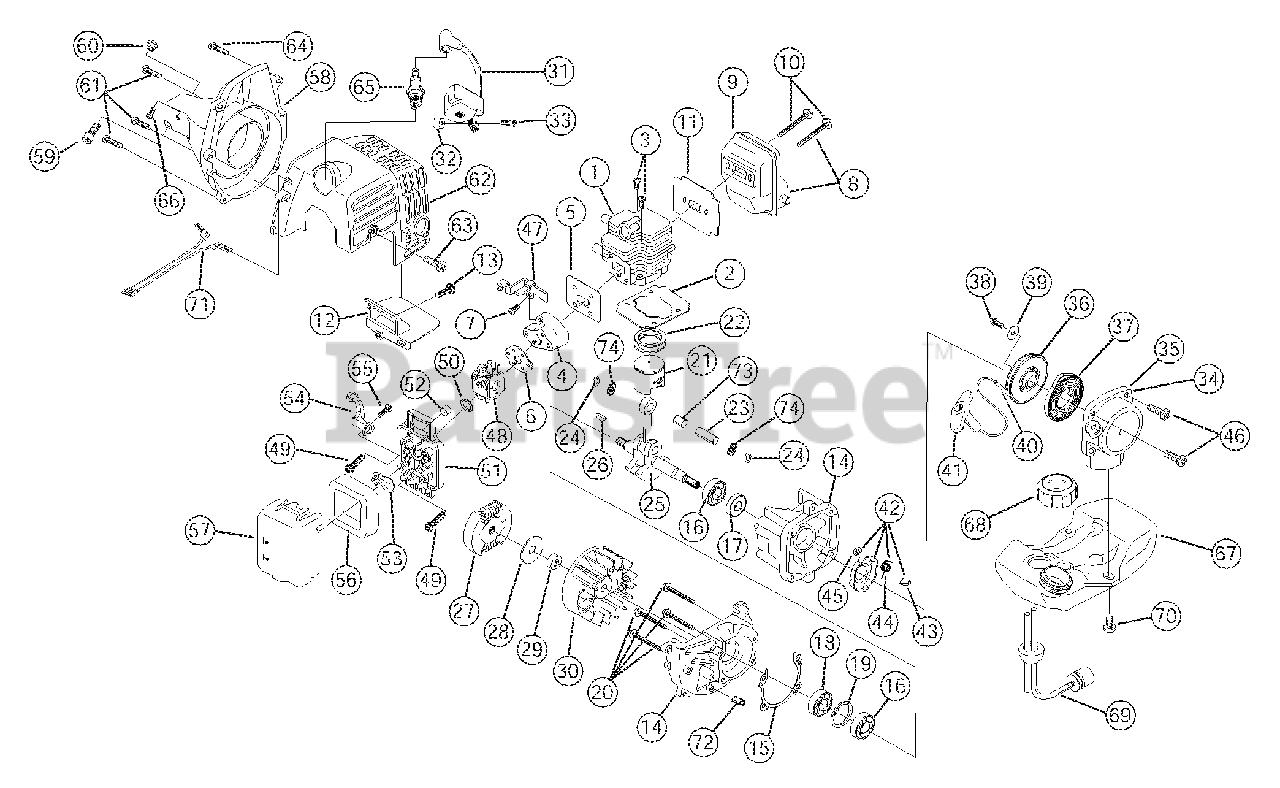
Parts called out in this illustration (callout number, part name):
2	Cylinder Base Gasket
5	Insulator Gasket
6	Carburetor Gasket
7	Screw and Washer
8	Muffler Assembly
11	Muffler Gasket
12	Muffler Plate
14	Crankcase Service Assembly
15	Crankcase Gasket
25	Crankshaft
28	Clutch Washer
30	Flywheel Assembly
31	Module Assembly
33	Screw
34	Recoil Assembly
35	Recoil Case
36	Recoil Pulley
37	Recoil Spring
41	Pull Handle
42	Pulley Assembly
45	Retaining Ring
47	Throttle Bracket
48	Carburetor
51	Air Cleaner Assembly
53	Choke Plate
54	Choke Lever
57	Air Cleaner Cover
58	Clutch Housing Assembly
62	Engine Cover
67	Fuel Tank
68	Fuel Cap Assembly
69	Fuel Line Assembly
71	Lead Wire Assembly
73	Needle Bearing
74	Piston Washer
